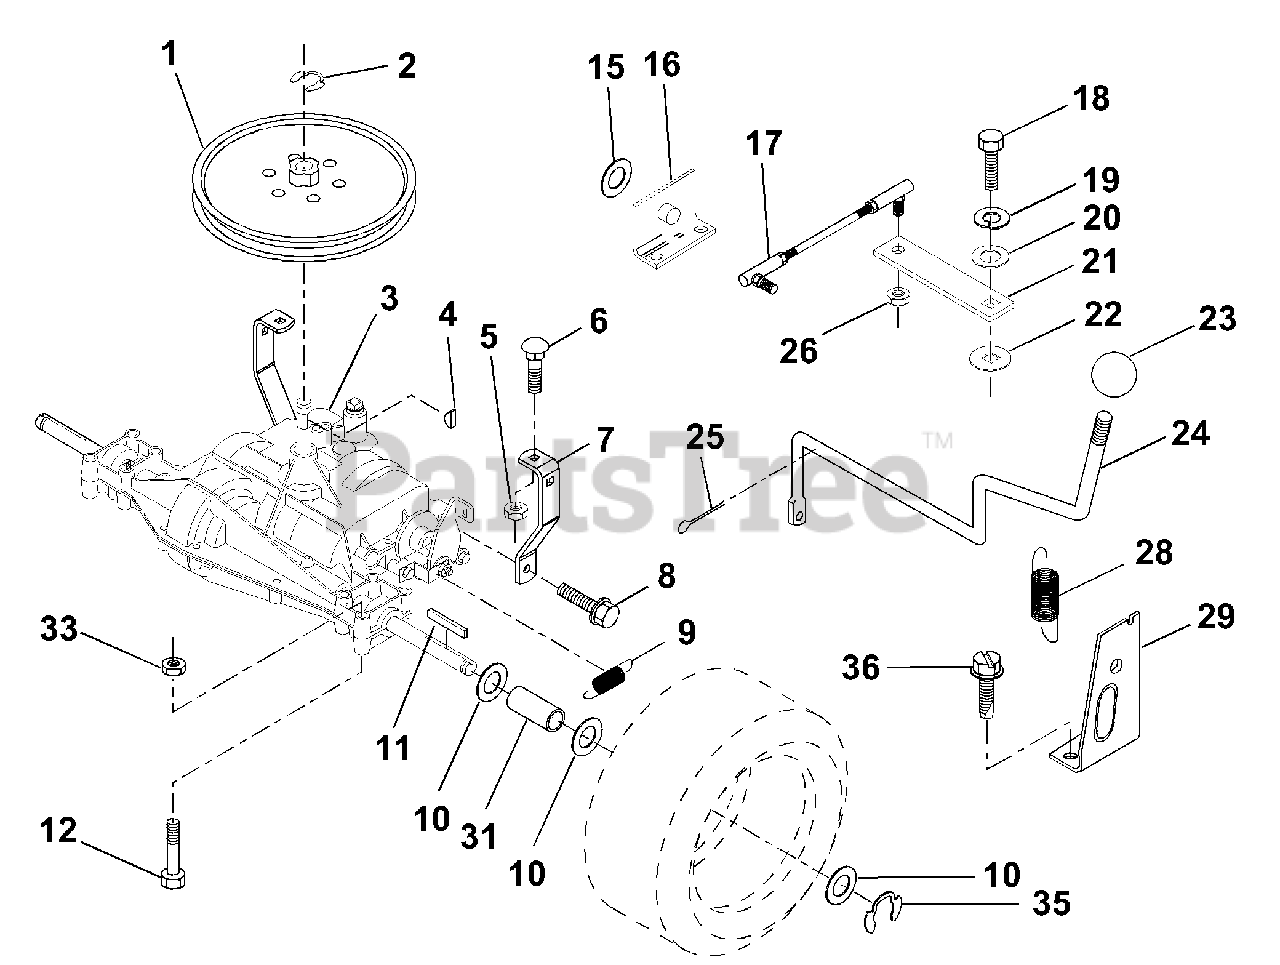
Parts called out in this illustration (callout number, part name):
2	Ring, Retainer
4	Key, Woodruff #9
5	Nut, Crownlock 5/16-18
6	Bolt, Carriage 5/16-18 UNC x 3/4
7	Strap, Torque
8	Screw 5/16-18 x 3/4
9	Spring, Brake
10	Washer 25/32 x 1-1/4 x 16 Ga.
11	Key, Square
12	Bolt, Fin Hex 3/8-16 Unc x 2-3/4
15	Washer 17/32 x 1 x 16 Ga.
16	Support Handle Shift LH
17	Link, Shift
18	Bolt, Fin Hex 1/4-28 UNF x 3/4 Gr. 8
19	Washer, Lock 1/4
20	Washer 9/32 x 3/4 x 10 Ga.
21	Arm, Shift
22	Washer, Shift Plate
23	Knob, Rd 1/2-13
25	Pin, Cotter 1/8 x 1
26	Locknut 5/16-24 UNF
28	Extension, Spring
29	Support Handle Shift RH
31	Spacer Axle
33	Nut Crownlock 3/8-16 Unc
36	Screw
